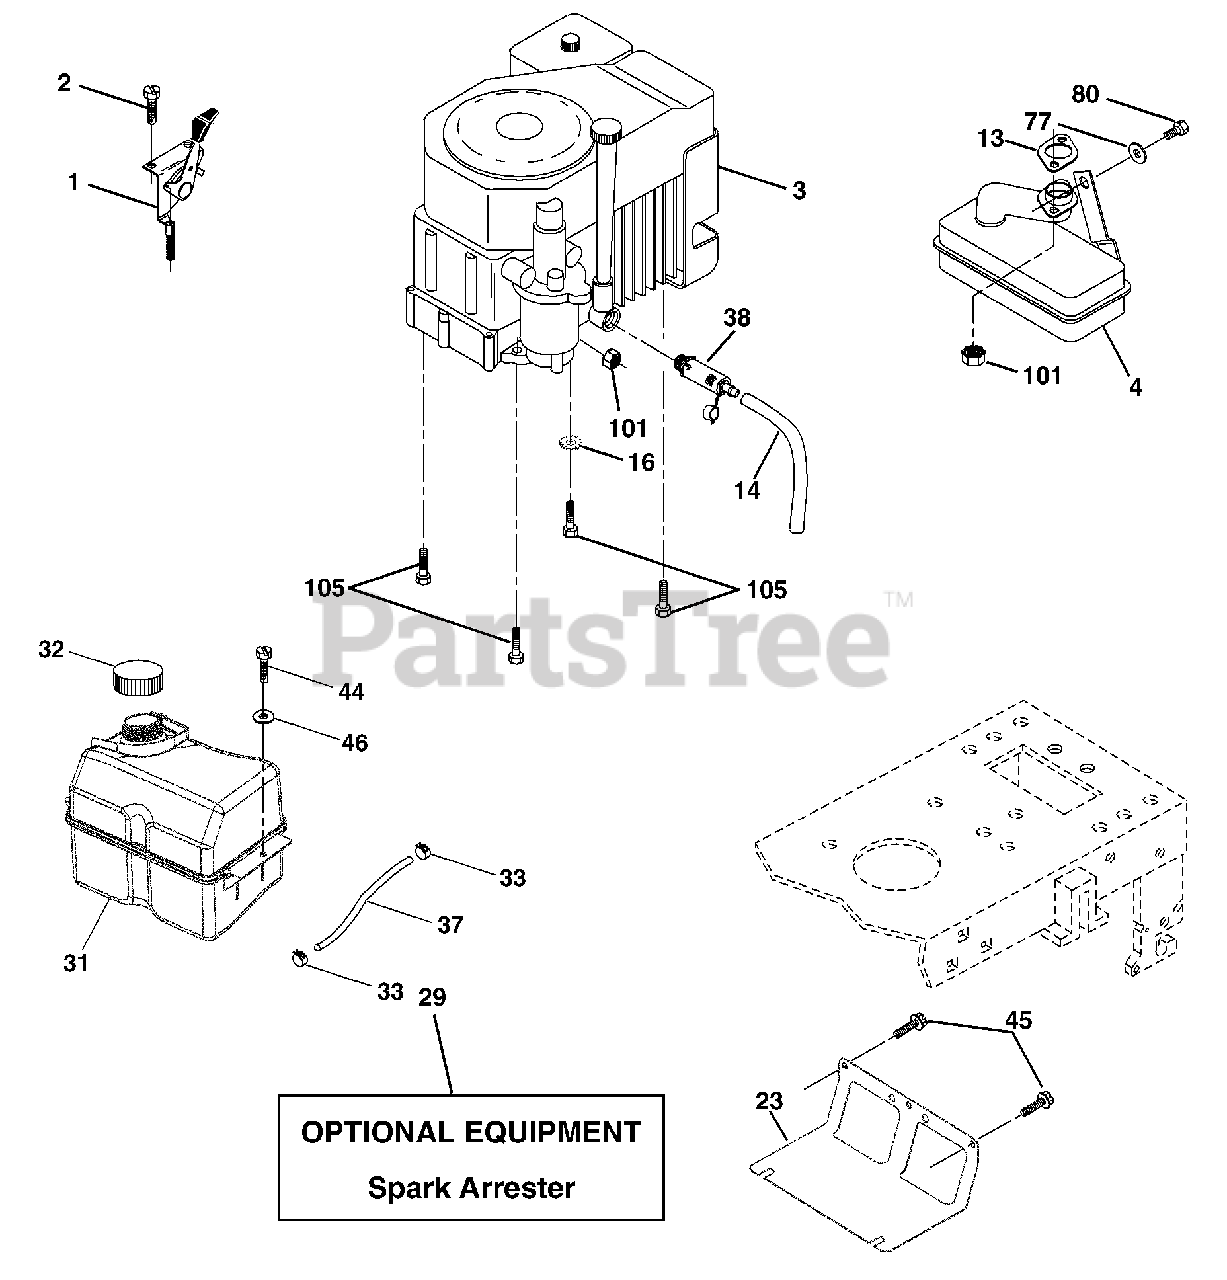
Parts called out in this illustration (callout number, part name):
1	Control Throt /Ch Flag
2	Screw Hex Thd Cut 1/4-20x1/2
4	Muffler Exhaust
14	Tube Drain Oil Easy
16	Washer Lock Ext Tooth 3/8
23	Shield Browning/Debris Guard
29	Arrestor Spark
31	Tank Fuel
32	Cap Asm Fuel W/sym Vented
33	Clamp Hose Blk
37	Line Fuel 20"
38	Plug Drain Oil Easy
44	Screw Hexwsh Thdrol 1/4-20x3/4
45	Screw Hex Wsh Thdrol 3/8-16
46	Washer 9/32 X 7/8 X 16ga
77	Washer 5/16 x 3/4 x 16 Ga.
80	Bolt Hex Hd 5/16-18 Unc x 1/2
101	Nut Flange
105	Screw 3/8-16 x 1
